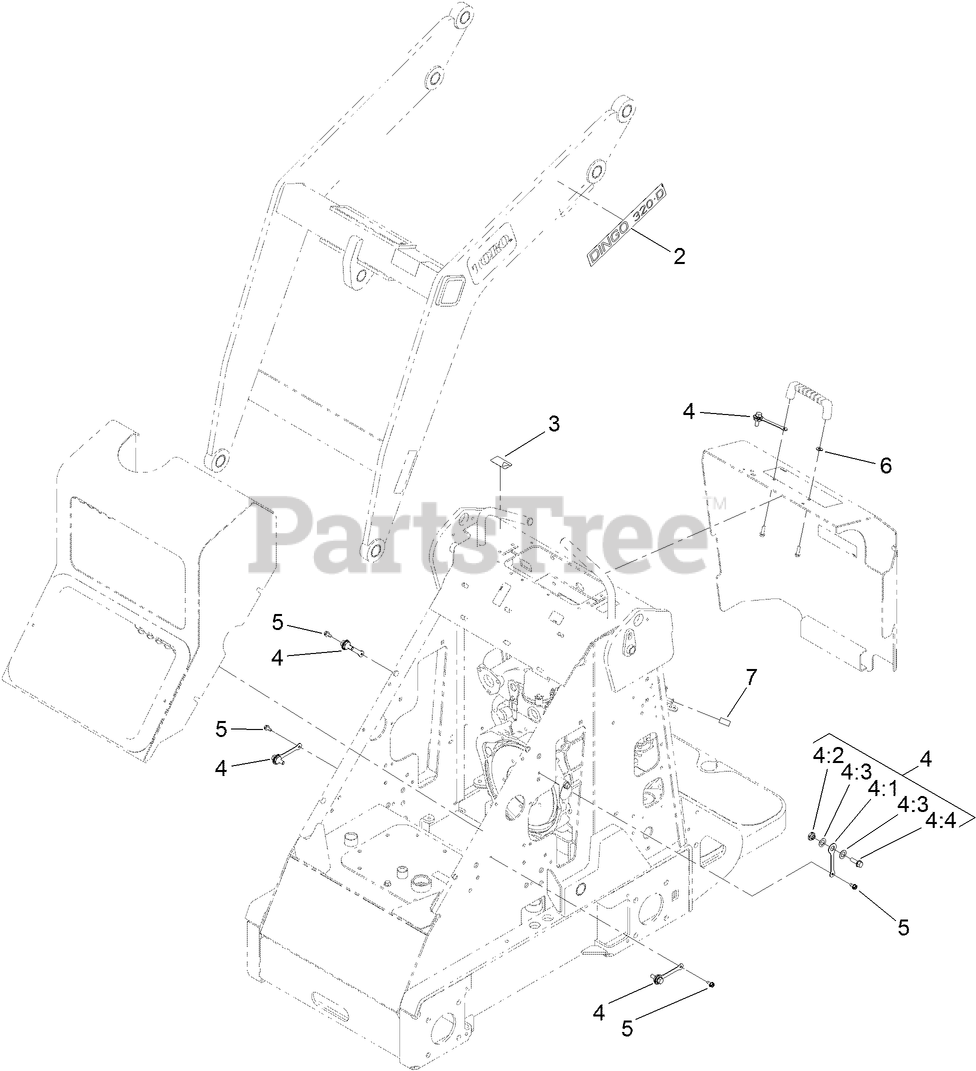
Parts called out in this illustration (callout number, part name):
2	DECAL
3	DECAL-PROTECTION, EAR
4	LANYARD ASM
4:1	LANYARD-3 INCH
4:2	NUT-SHOULDER
4:3	WASHER
4:4	SCREW-HHF
5	SCREW-HWH
6	WASHER-FLAT
7	TUBE-ALUMINUM
